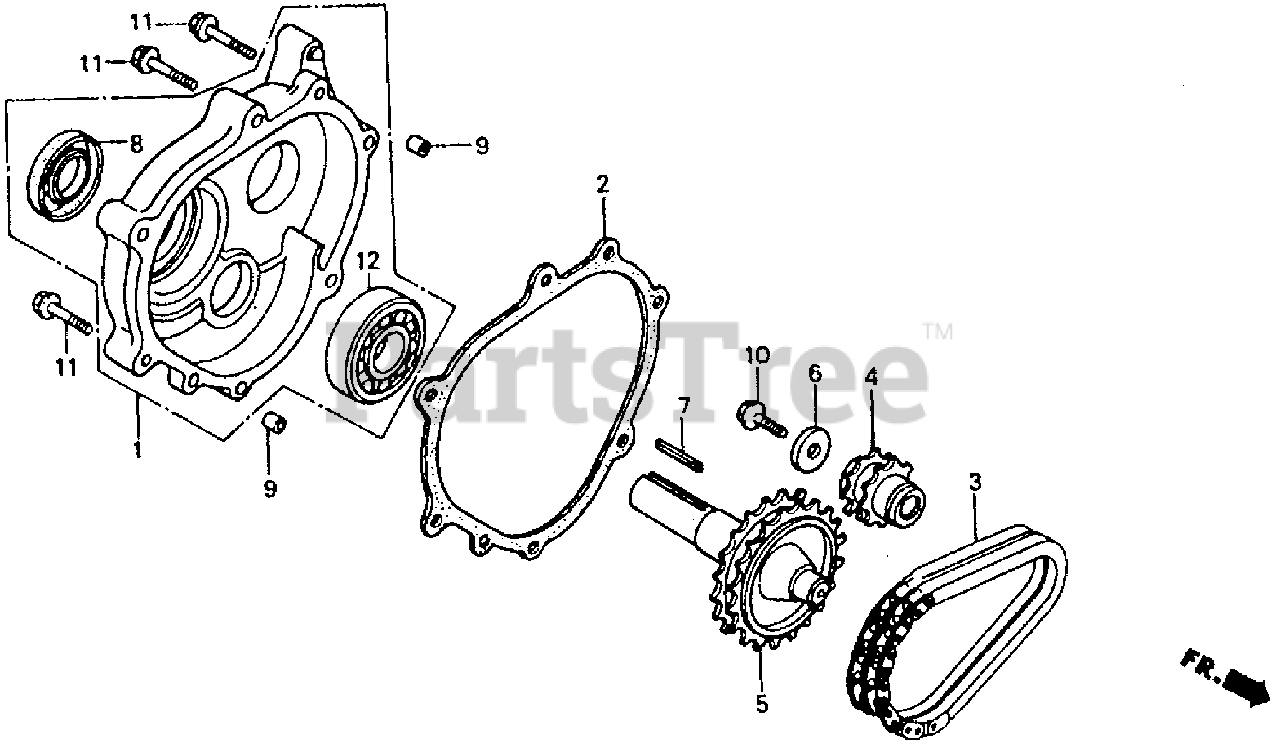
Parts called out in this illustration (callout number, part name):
1	COVER ASSY., CHAIN CASE
2	GASKET, CHAIN CASE COVER
3	CHAIN, P.T.O. DRIVE
4	SPROCKET, DRIVE (14T)
5	SHAFT, P.T.O. (28T) (L-TYPE)
6	WASHER (8MM)
7	KEY (7X7X33)
8	OIL SEAL (30X46X8)
9	PIN, DOWEL (8X12)
9	PIN A, DOWEL (8X12)
10	BOLT, FLANGE (8X25)
11	BOLT, FLANGE (8X40)
12	BEARING, RADIAL BALL (6206)
